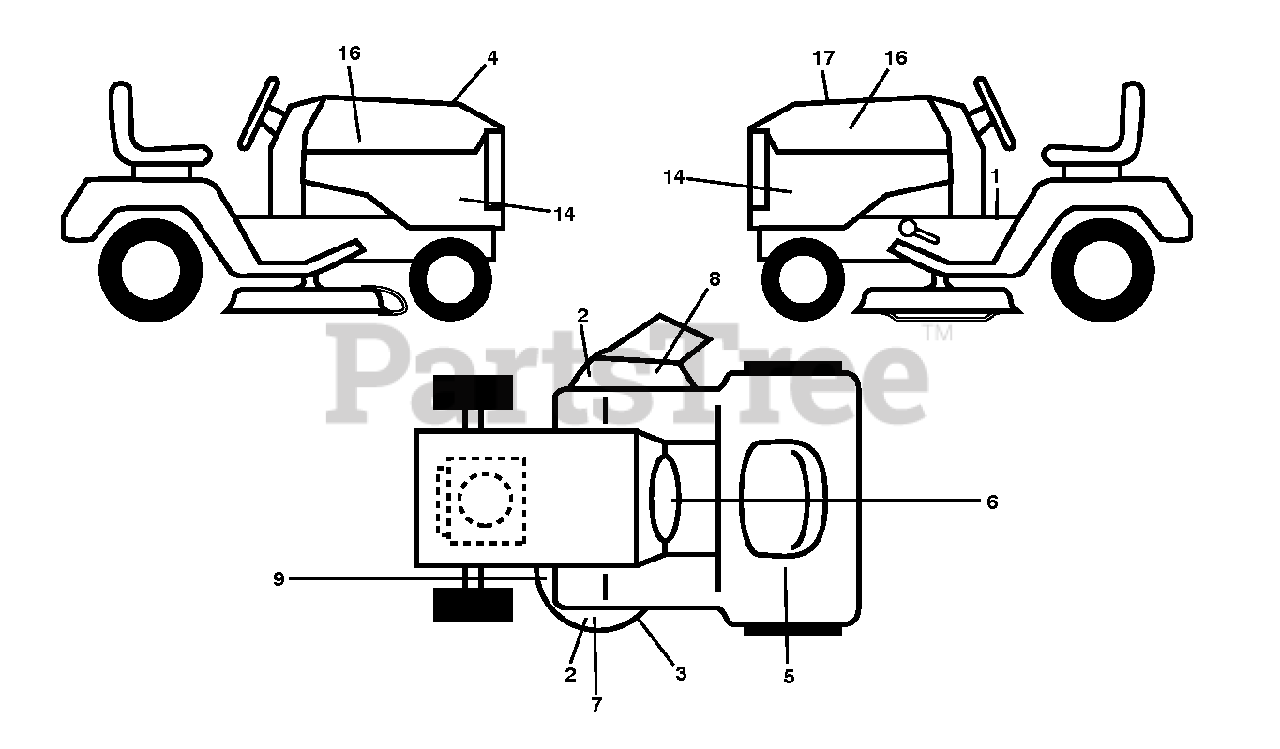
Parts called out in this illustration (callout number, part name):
1	DECAL.FENDER.WARNING.ENGLISH
2	DECAL.DECK.CLEARCUT.NOSTEP
3	DECAL.MOWER.SCH.48/54.PREM
4	DECAL.WARNING.CUST.RESP.E85.
5	DECAL.RESERVEFUELSELCTR.ENG
6	Warning Decal, Spark Arrest
7	Deck Decal, 48"
8	DECAL.TRACT/ZTR.DECKWARN.HUSQ
9	Deck Decal, WA
14	Tractor Side Panel Decal
16	DECAL.BADGE.170MM.TEXTLOGO.
17	DECAL RPL K66.48F.KOH KT7.TGB
